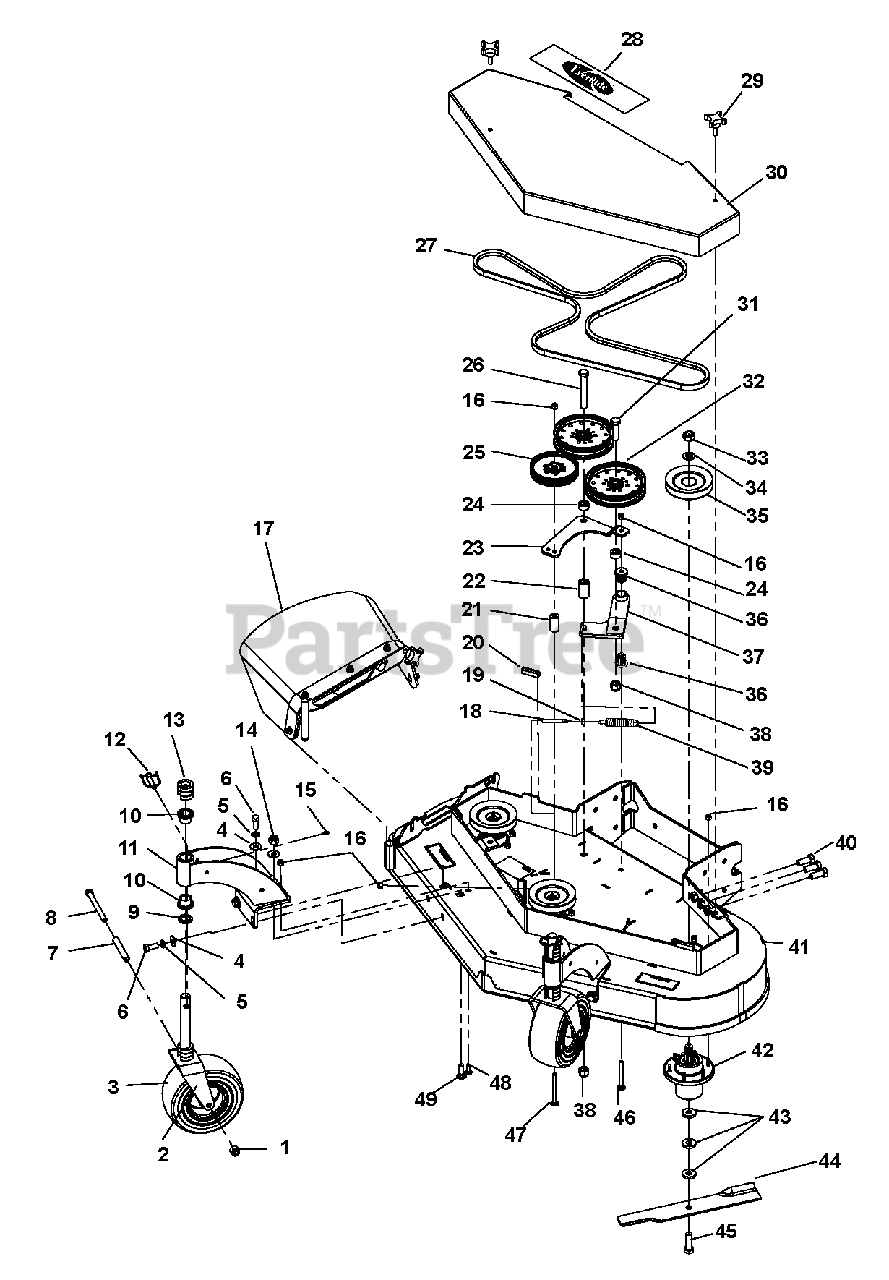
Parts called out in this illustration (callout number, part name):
1	Locknut, .50-13 Nyloc
2	Weldment, Caster Yoke
3	Assembly, Wheel & Tire - 9 x 3.5-4
4	Washer, .438 Regular Flat
5	Washer, .500 Medium Spring Lock
6	Bolt, .50-13 x 1.25 Hex Grade 5
7	Tube, Caster Axle
8	Bolt, .50-13 x 5.50 Grade 5
9	Bushing, 1.03 x 1.50 x .179
10	Bearing, Flange 1.00 x 1.25 x 1.00
11	Weldment, Strut Front Wasp
12	Pin, LNC .438 x 2.00
13	C-Spacer, 1.00 x 1.77 x .500
14	Locknut, .50-13 Nyloc
15	Fitting, .25-28 Straight Grease Zerk
16	Locknut, .375-16 Nyloc
17	Assembly, Discharge Shield
18	Rod, Threaded Adjustment
19	Locknut, .375-16
20	Trim, 2" Trim-Lok Edge
22	Bushing, .688 x 1.13 x 1.89
23	Strap, Idler 52 FXWLK
24	Bushing, .688 x 1.13 x .55
25	Pulley, Flat 5.00 x .375 w/Bearing
26	Bolt, .62-11 x 4.50 Hex Grade 5
27	Belt, HB 114.9 Elbow AMD
28	Decal, 9" EverRidge Logo Small
29	Knob, .375 x 1.25 - 4 Prong
30	Weldment, Belt Shield 48 FXWLK
31	Bolt, .62-11 x 2.25 Hex Grade 5
32	Pulley, Flat 6.00 x .635 w/Bearing
33	Locknut, .75-16 Crown
34	Washer, .75 x 1.3125 x .113
35	Pulley, Spline Spindle Offset
36	Bearing, Flange M10 x M25 x M27 Fluted
37	Weldment, Idler Arm FXWLK
38	Nut, Lock, Nylon .625-11
39	Spring, Ext .875 x .125 x 4.25
40	Bolt, .625-11 x 1.50 Hex Grade 8
41	Assembly, Deck 48 Wasp w/Decals
42	Assy, Spindle Housing
43	Washer, Blade
44	Blade, 16.50 Lo-Lift
45	Bolt, .625-11 x 2.00 Hex Grade 8
46	Bolt, .375-16 x 3.50 Grade 5
47	Bolt, 3/8 x 4 SHT NK RD HD
48	Bolt, .375-16 x 1.00 Grade 5
49	Bolt, .50-13 x 1.50 Round Head Square Neck Grade 5
